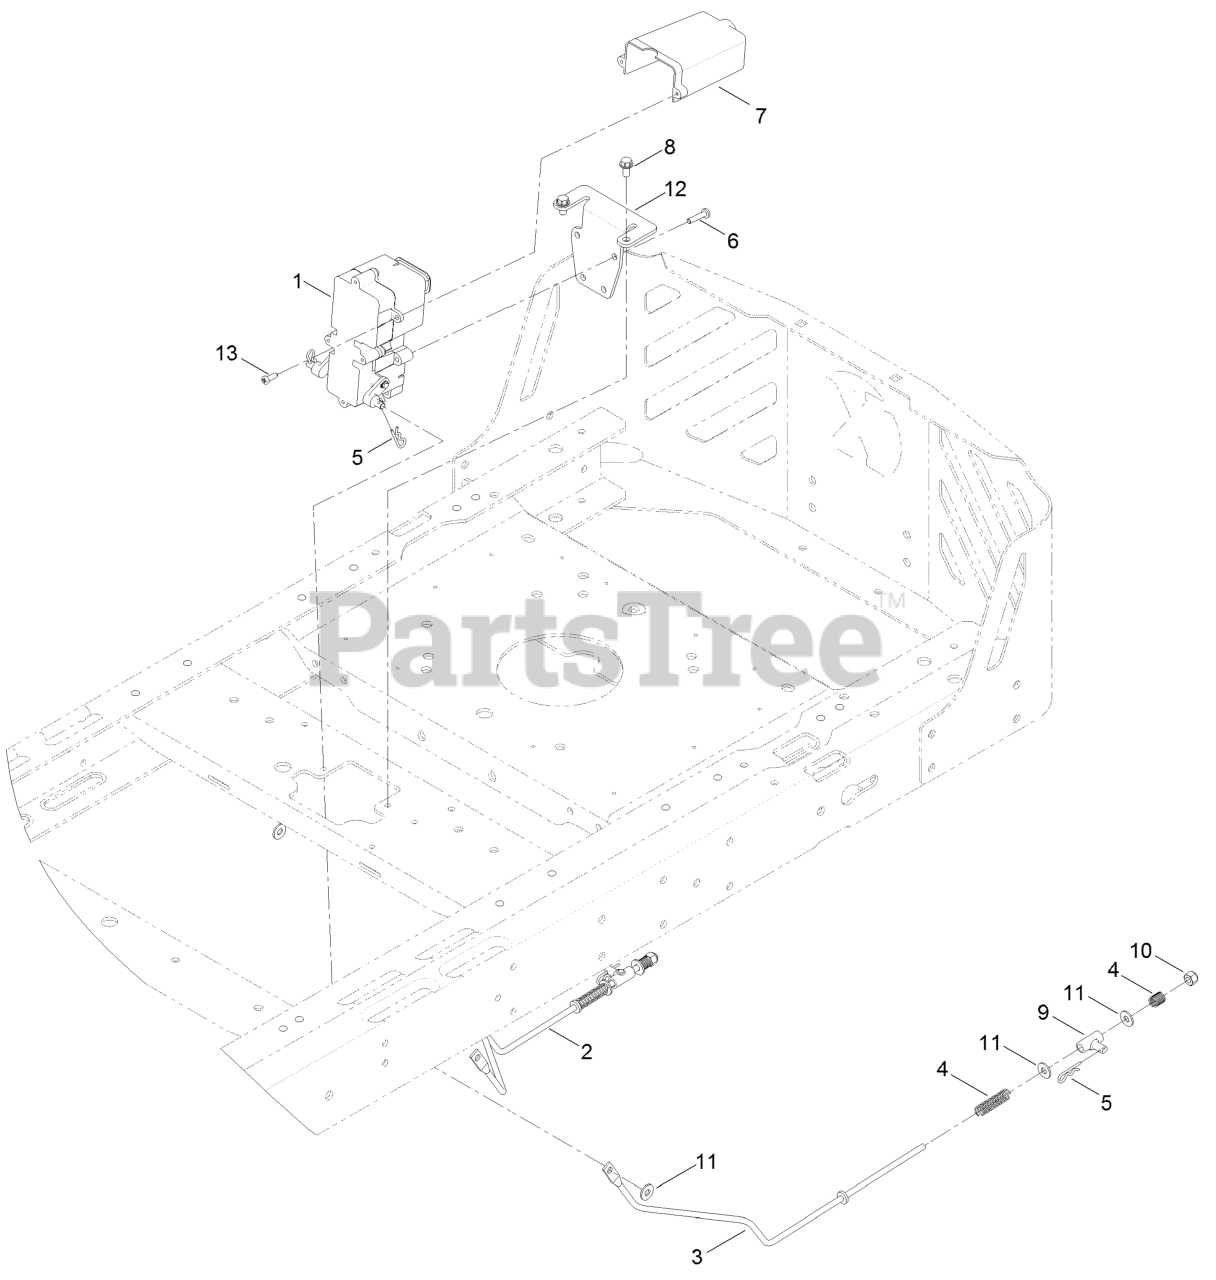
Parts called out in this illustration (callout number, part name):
2	ROD-BRAKE, RH
3	ROD-BRAKE, LH
4	SPRING-COMPRESSION
6	SCREW-PPH
8	SCREW-HWH
9	MOUNT-PIVOT
10	NUT-LOCK, NI
12	BRACKET-MOUNT, BRAKE
13	SCREW-PPH
